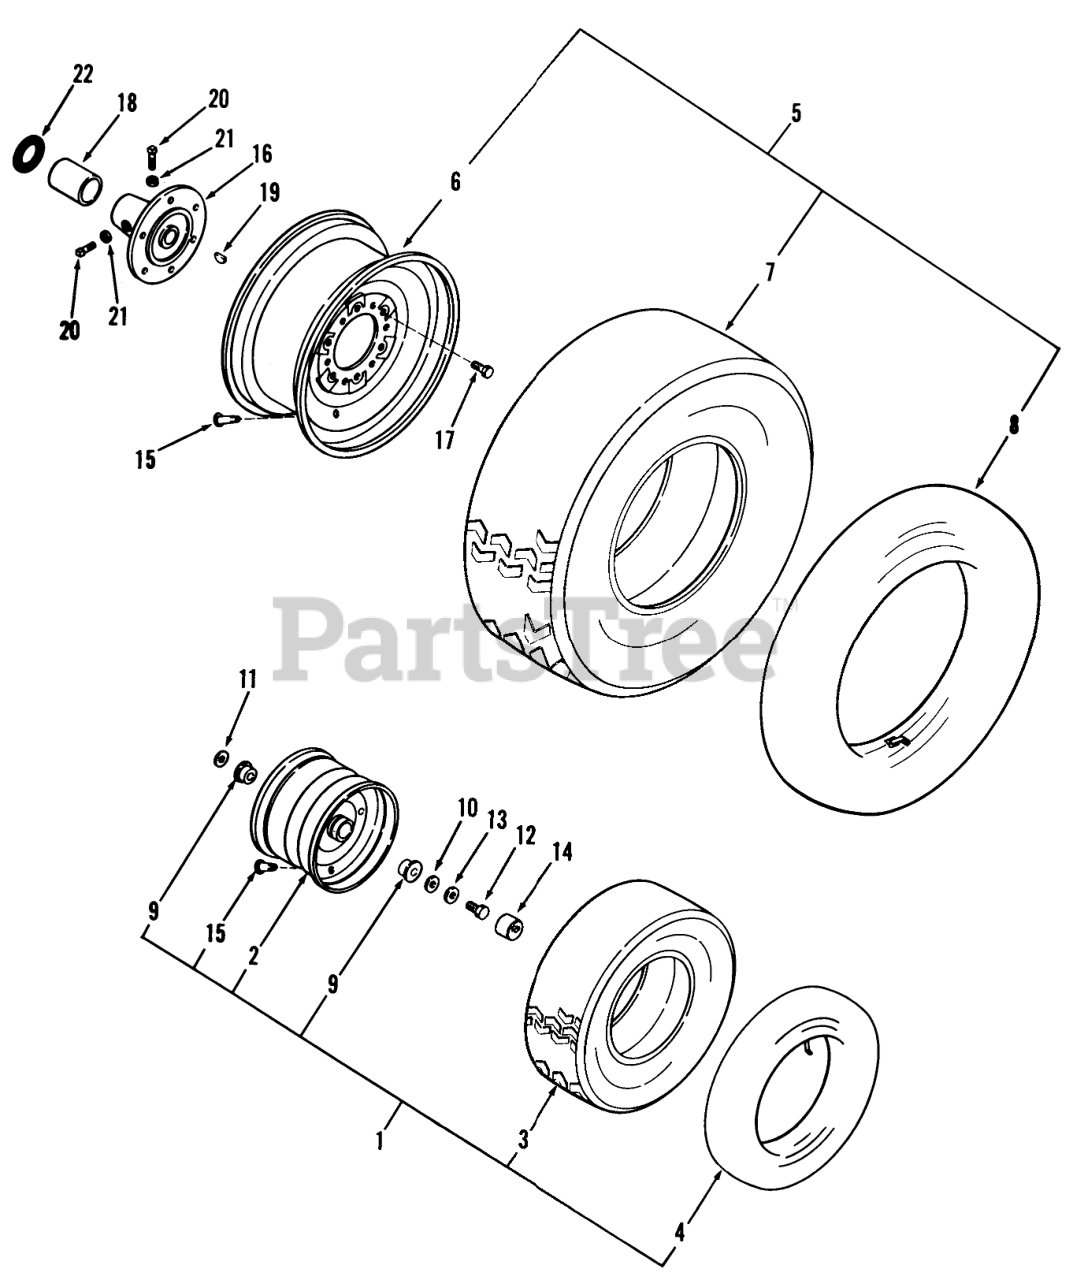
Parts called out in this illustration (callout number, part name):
1	ASSY-WHEEL
4	TUBE-TIRE
8	Yoke
10	WASHER
13	WASHER
15	VALVE
17	BOLT-LUG, WHEEL
22	WASHER-THRUST
